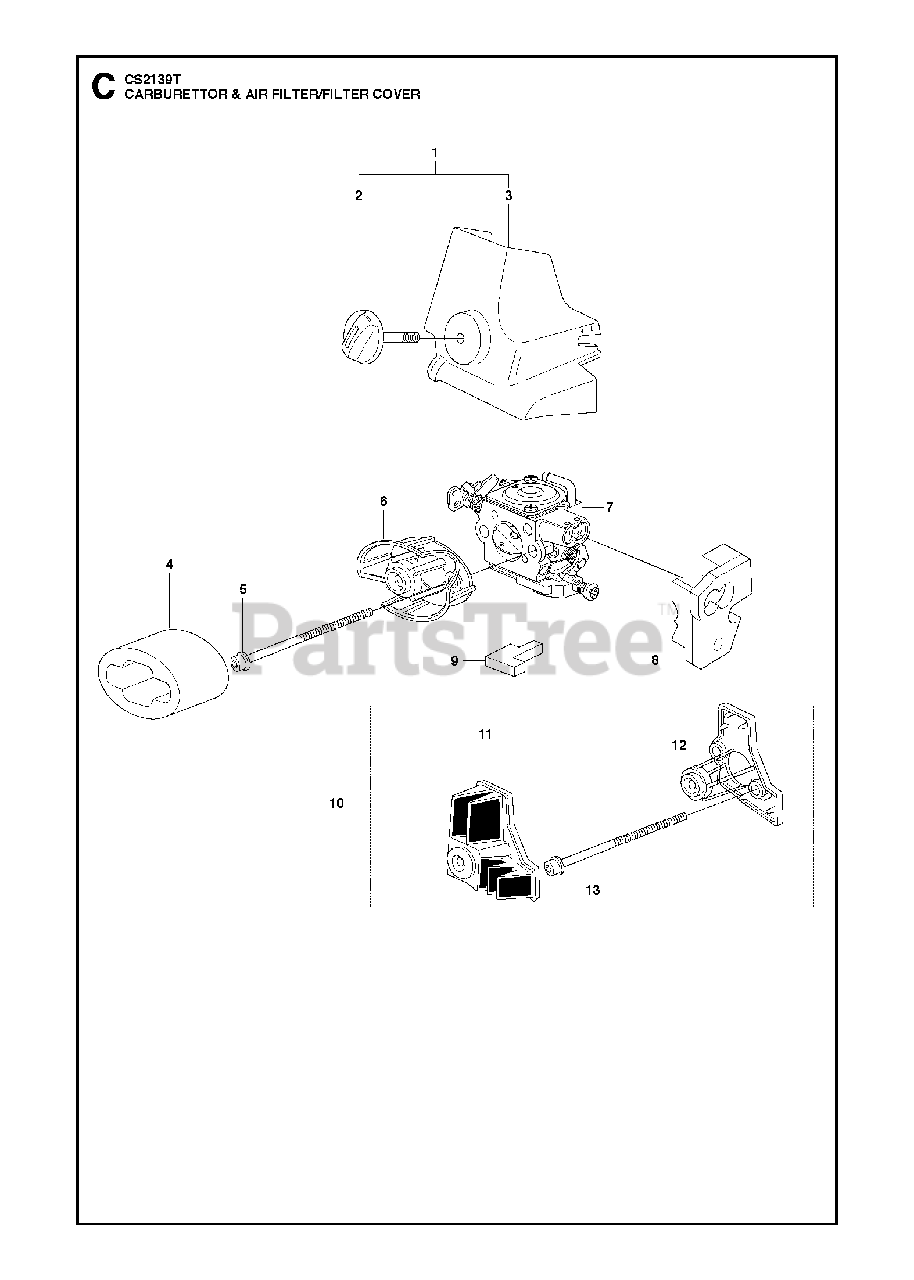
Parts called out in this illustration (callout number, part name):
1	AIR FILTER COVER
2	KNOB
3	AIR FILTER COVER
4	AIR FILTER
7	CARBURETOR
10	AIR FILTER
10	AIR FILTER KIT
11	AIR FILTER
12	BASE
12	FILTER HOLDER
13	SCREW
